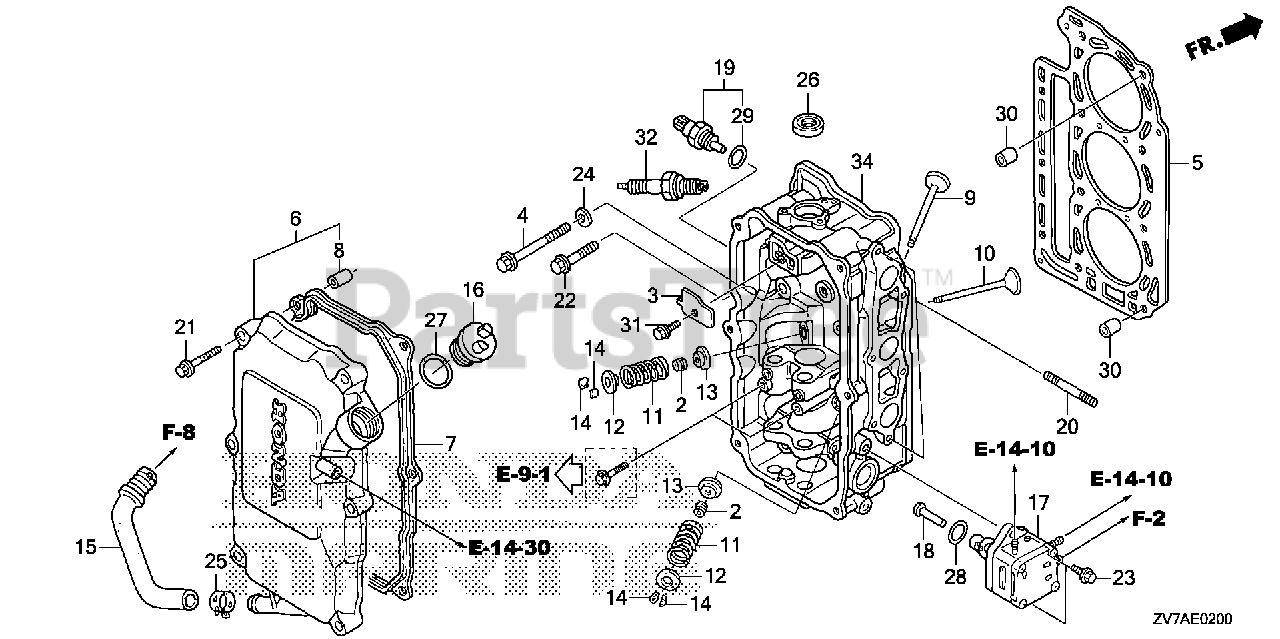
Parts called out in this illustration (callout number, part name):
2	SEAL, VALVE STEM (ARAI)
3	PLATE, OIL CHAMBER
4	BOLT, FLANGE (8X83)
5	GASKET, CYLINDER HEAD
6	COVER, CYLINDER HEAD
7	GASKET, HEAD COVER
8	COLLAR, HEAD COVER
9	VALVE, IN.
10	VALVE, EX.
11	SPRING, VALVE
12	RETAINER, VALVE SPRING
13	SEAT, VALVE SPRING
14	COTTER, VALVE
17	PUMP ASSY., FUEL (MSDS)
18	LIFTER, FUEL PUMP
19	SENSOR ASSY., WATER TEMPERATURE
20	BOLT, STUD (6X28)
21	BOLT, FLANGE (6X35)
22	BOLT, FLANGE (8X40)
23	BOLT, FLANGE (6X20)
24	WASHER, PLAIN (8MM)
25	CLAMP, TUBE (D17)
26	OIL SEAL (20X32X6)
27	O-RING (26X2.7)
28	O-RING (20.8X2.4)
29	O-RING (9.5X1.5) (HONDA KIKAKI)
30	PIN, DOWEL (10X12)
31	BOLT, FLANGE (6X12)
32	SPARK PLUG (DR7EA) (NGK)
32	SPARK PLUG (X22ESR-U) (DENSO)
34	CYLINDER HEAD *NH8* (DARK GRAY)
